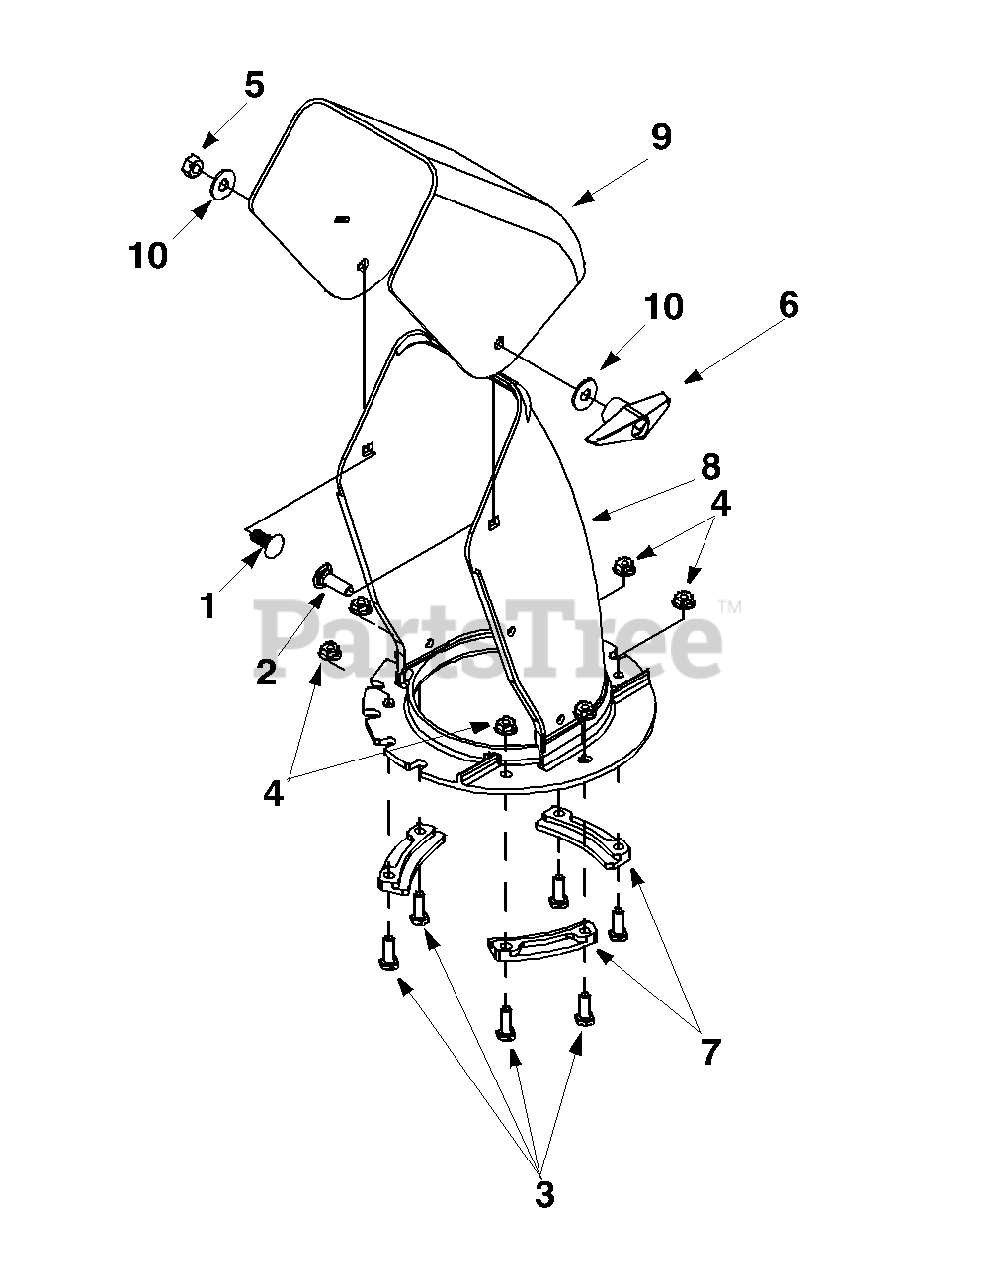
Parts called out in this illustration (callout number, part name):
1	Carriage Bolt 5/16-18 x 1.0"
2	Carriage Bolt 5/16-18 x 0.750"
3	Hex Screw 1/4-20 x 0.75"
4	Lock Nut
5	Hex Lock Nut
6	Hand Knob
7	Flange Keeper: Chute
8	Lower Chute
9	Upper Chute
